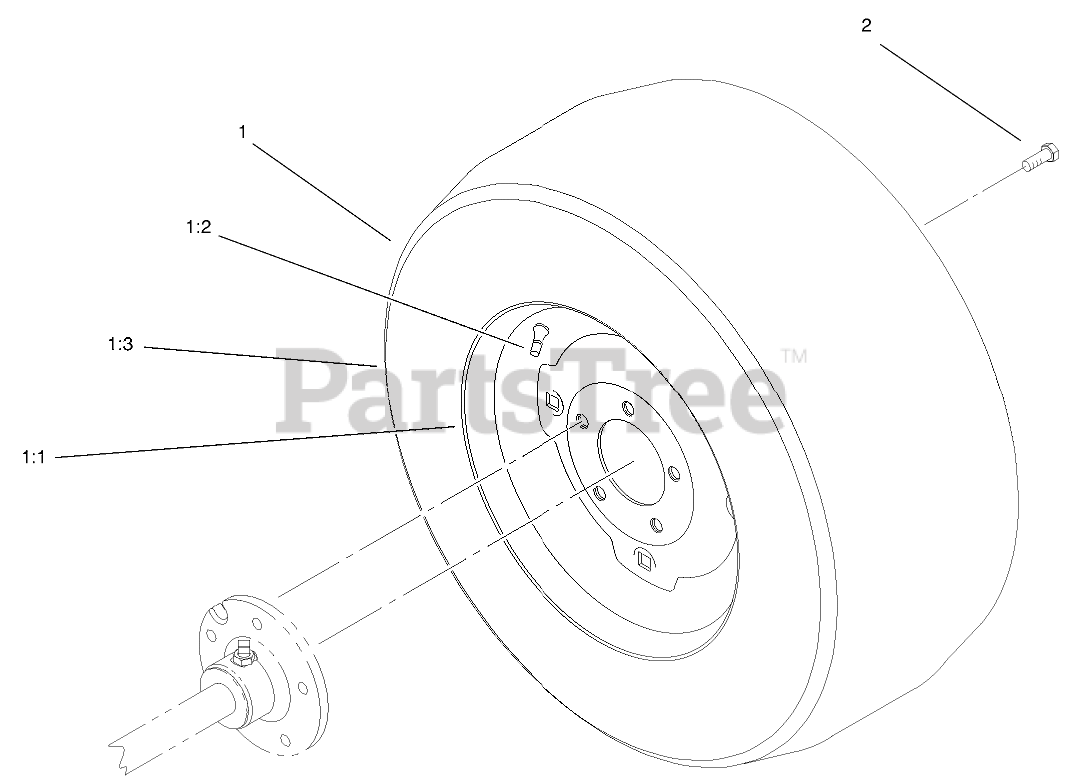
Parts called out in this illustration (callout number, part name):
1	Rear Wheel & Tire ASM (Only On: 73550)
1	Rear Wheel & Tire ASM (Only On: 73551)
1:1	Tire (Only On: 73550)
1:1	Tire (Only On: 73551)
1:2	VALVE
1:3	RIM ASM
2	BOLT-LUG
